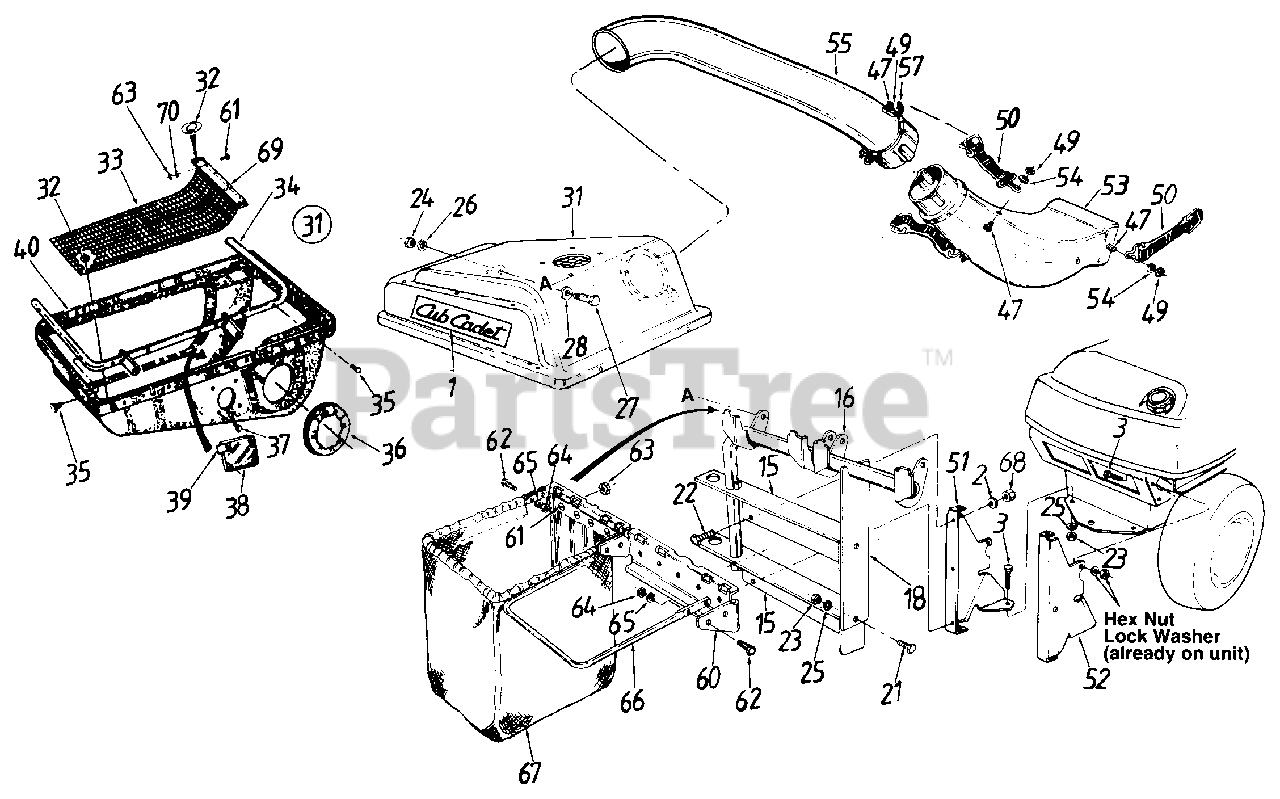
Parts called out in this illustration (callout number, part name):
1	Cub Cadet Name Plate
2	Fl-Wash. 1/4" I.D.
3	Hex Bolt 5/16-18 x 1.0" Lg.
15	Catcher Support Tube Mtg. Brkt.
16	Catcher Support Tube Ass'y.
18	Catcher Latch and Support Brkt.
21	Hex Bolt 5/16-18 x .75"
22	Hex Bolt 1/4-20 x .62" Lg.--Grade 5
23	Hex Nut 5/16-18 Thd.
24	Hex Nut 3/8-16 Thd.
25	L-Wash. 5/16" I.D.
26	L-Wash. 3/8" I.D.
27	Shld. Bolt 3/8-16 x .50" Dia.
28	Bell-Wash. .505" I.D.
31	Grass Catcher Cover Ass'y.
32	Twist Fastener
35	Hex Tap Scr. 1/4-20 x .5"
36	Seal
37	Truss Mach. B-Tap Scr. #10 x .5" Lg.
38	Plastic Plate
39	Speed Nut
40	Grass Catcher Cover
47	Hex Bolt 1/4-20 x .50"
49	Hex Ins. L-Nut 1/4-20 Thd.
50	Retainer Strap Ass'y.
51	Catcher Support Brkt.--L.H.
52	Catcher Support Brkt.--R.H.
53	Discharge Chute
54	L-Wash. .270" I.D.
55	Catcher Tube
57	Retainer Hook Brkt.
61	Truss Mach. Scr. #10-24 x .50" Lg.
62	Hex Bolt 1/4-28 x .75"
63	Hex Sems Nut #10-24 Thd.
64	Hex Nut 1/4-28 Thd.
65	L-Wash. 1/4" I.D.
67	Grass Catcher Bag
68	Hex L-Nut 1/4-20 Thd.
69	Screen Mtg. Brkt.
70	Fl-Wash. 1/4" I.D.
